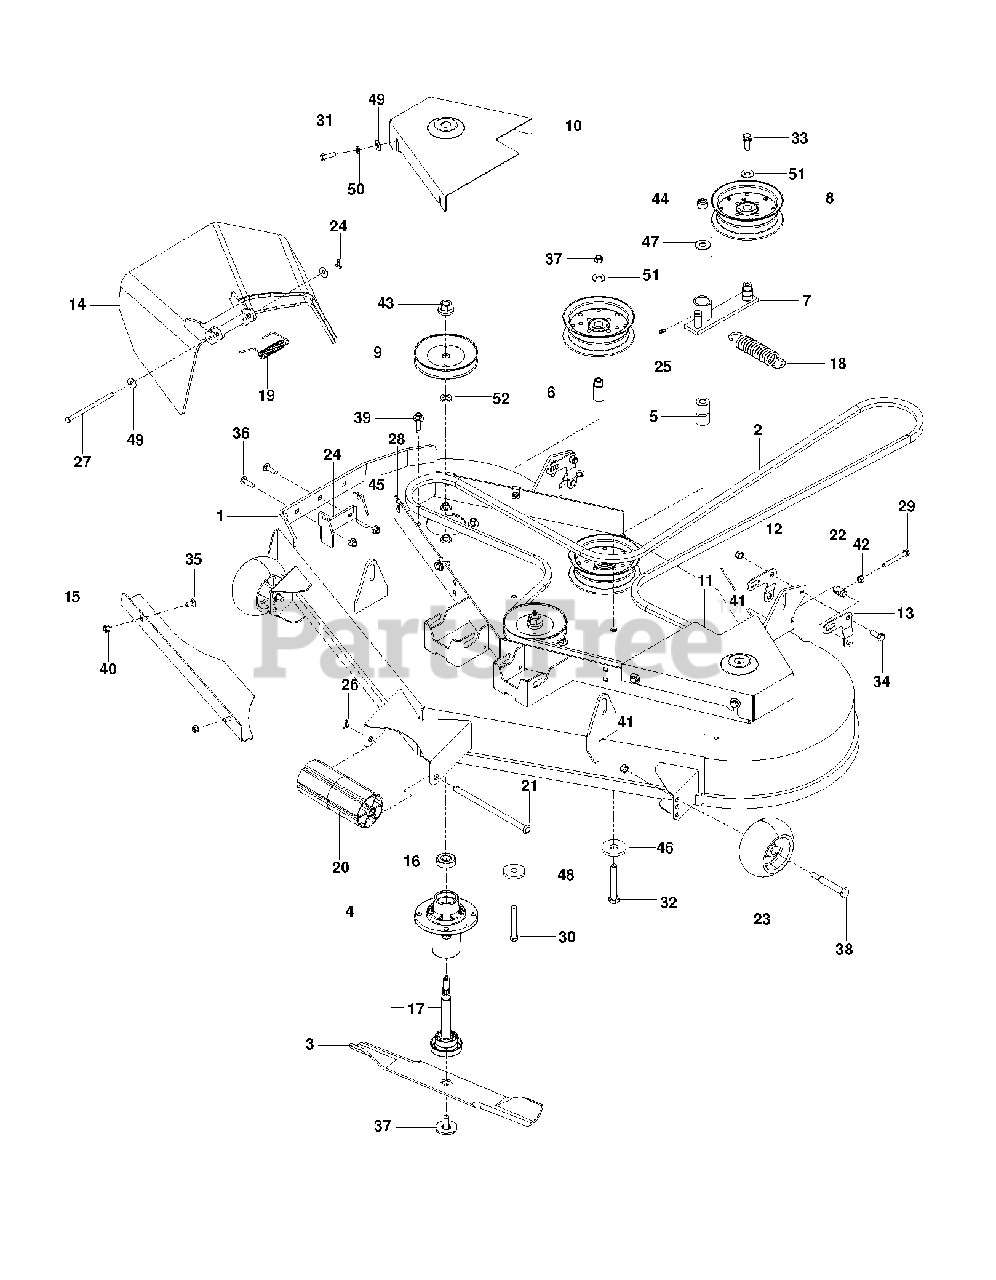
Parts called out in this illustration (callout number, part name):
3	BLADE, 18"
4	MANDREL ASM, CAST IRON
5	PIVOT BUSHING
6	IDLER BUSHING
7	IDLER ARM
8	PULLEY, IDLER
9	PULLEY MANDREL
10	SHIELD, BELT 52 BLUE RH
11	SHIELD, BELT 52 BLUE LH
12	PITCH, ADJUST, RT
13	PITCH, ADJUST, LT
14	DISCHARGE CHUTE 52"
15	CONFINEMENT PLATE, 52"
16	BEARING
17	SHAFT ASM MANDREL
19	SPRING - TORSION
20	NOSE ROLLER 48"
21	ROD.ROLLER.NOSE.NARROW.48"
22	TRUNION, PITCH
25	ZERK
26	COTTER PIN 1/8 X 3/4
27	PIN-CLEVIS 5/16 DIA X 5.19 ZD
28	U-CLIP 5/16-18 NUT RETAINER
29	HCS 5/16-18 X 2 1/2 TPBLT
30	HCS 3/8C X 3
31	HCS 5/16C X 3/4
32	HCS 1/2C X 3 1/4
33	HCS 3/8C X 1 SERRATED HEAD
34	HCS 3/8C X 1
35	CARRIAGE BOLT 5/16C X 5/8"
36	RHSSNB 5/16C X 1.0
39	SCREW, WASHER HEAD
40	NUT 5/16 NYLOC
41	NUT 3/8-16 NYLOC
42	NUT 5/16C HEX
44	NUT 1/2-13 HEX NYLOC ZD
45	5/16-18 NYLOC FLANGE NUT
46	WASHER, SUPPORT
47	WASHER 1/2 FLAT
48	SPINDLE WASHER
49	WASHER 5/16 FLAT
50	WASHER 5/16 LOCK
51	WASHER 3/8 FLAT
